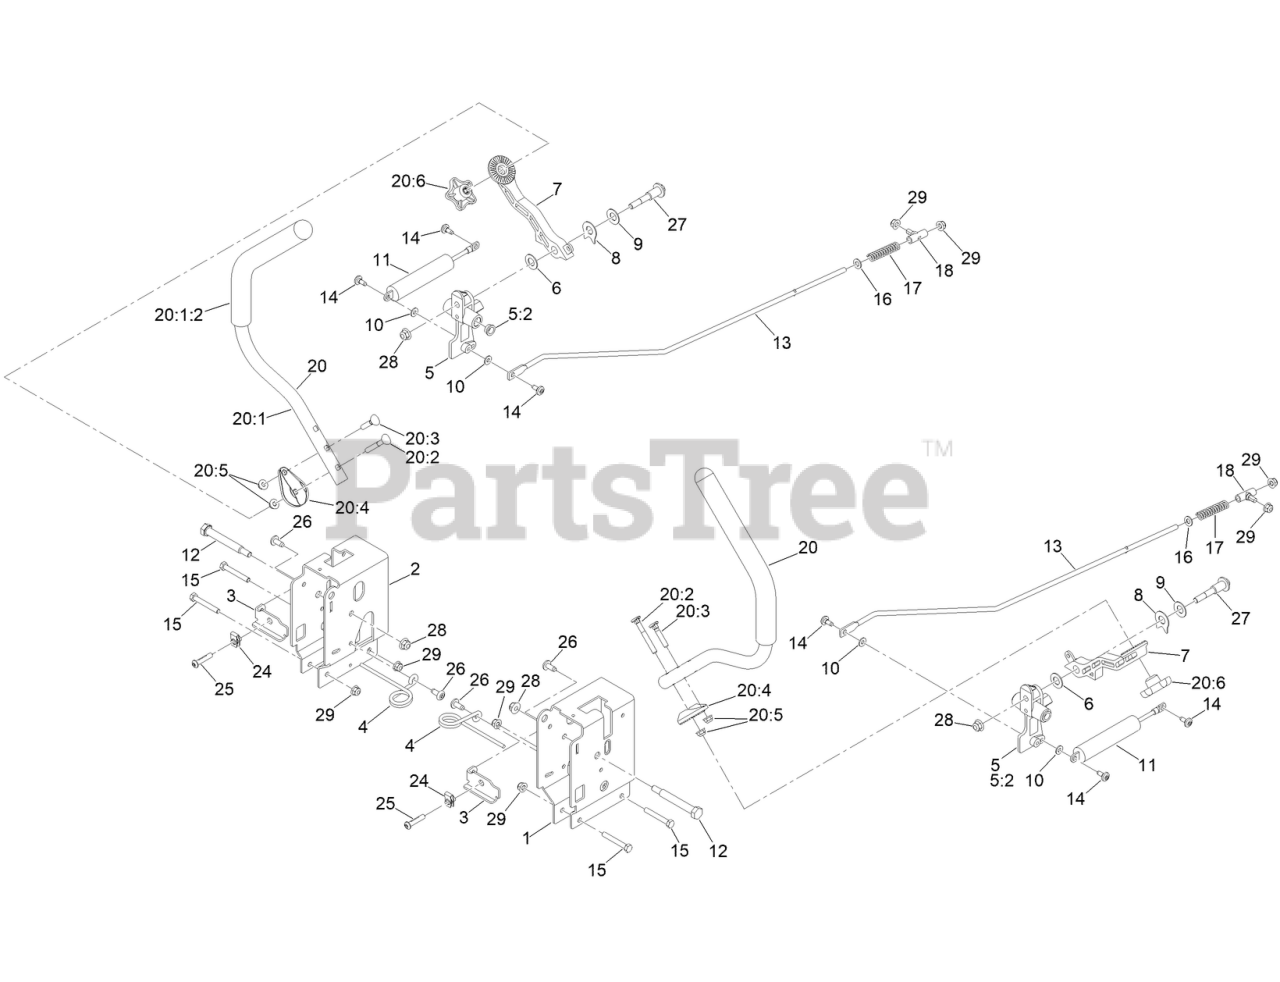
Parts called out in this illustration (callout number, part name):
1	CONTROL BOX - LH G7
2	CONTROL BOX - RH G7
3	ADJUSTMENT PLATE-CONTROL BOX
4	SPRING-TORSION
5	PIVOT ARM ASM
5:2	BUSHING-FLANGE
6	WASHER-NYLON
7	ARM-CONTROL, 32 TEETH
8	SPACER, ANTI-ROTATION
9	WASHER-BELLEVILLE
10	WASHER
11	DAMPER - NON CAVITATING
12	BOLT-PIVOT
13	ROD-HYDRO
14	SCREW-SHOULDER
15	SCREW-HH
16	WASHER-PLAIN
17	SPRING-COMPRESSION
18	MOUNT-ROD, HYDRO
20	CONTROL HANDLE ASM
20:1	HANDLE-CONTROL
20:2	SCREW-HANDLE
20:3	SCREW-HANDLE
20:4	DISC-ADJUSTMENT HANDLE, 32 TEETH
20:5	NUT-HF
20:6	KNOB-HANDLE
25	SCREW-HSBH
27	BOLT-PIVOT
28	NUT-HF, NI
29	NUT-HF, NI
